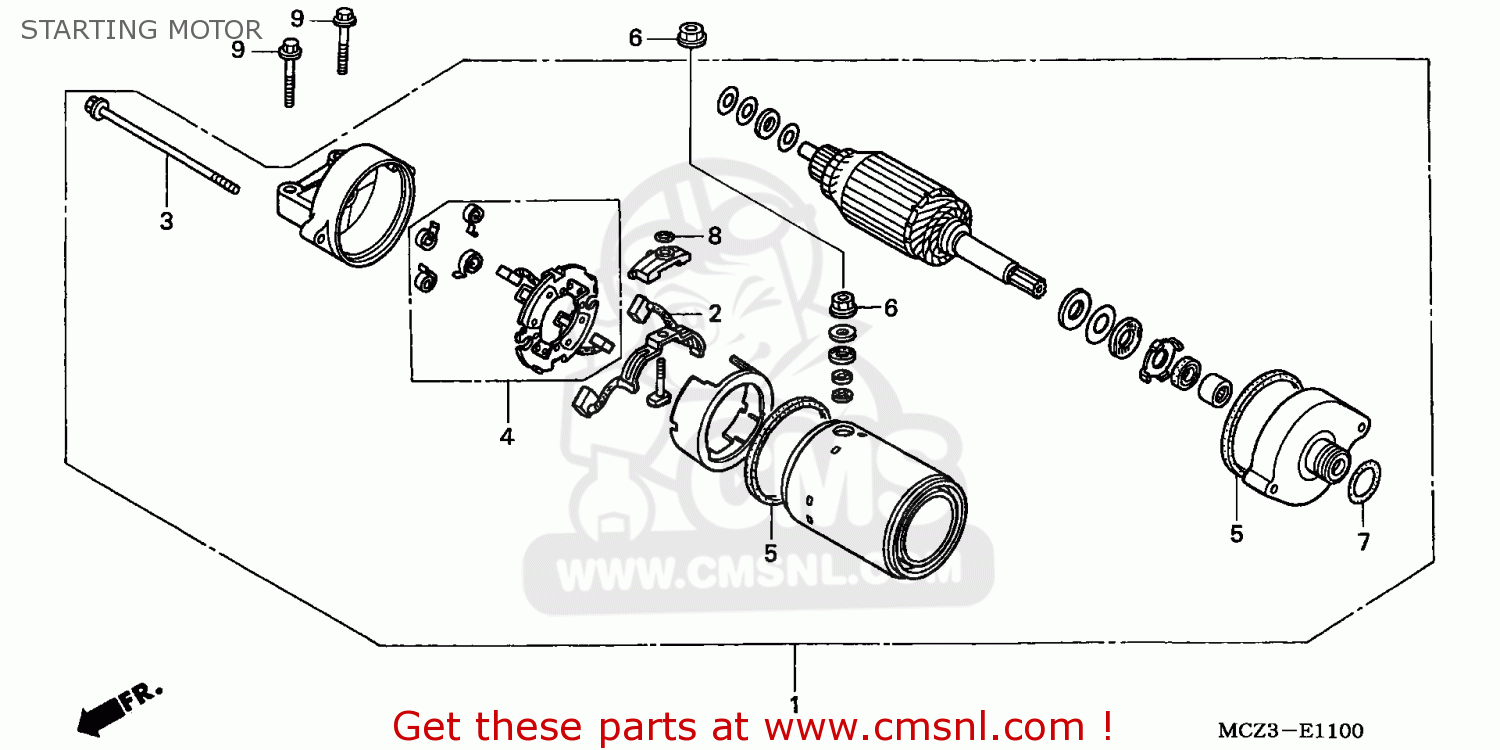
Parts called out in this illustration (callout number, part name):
1	MOTOR ASSY.,START
2	TERMINAL SET
3	BOLT,SETTING
4	HOLDER SET,BRUSH
5	RING
6	NUT-WASHER 6MM
7	O-RING,24.4X3.1
8	O-RING
9	BOLT,FLANGE,6X28
